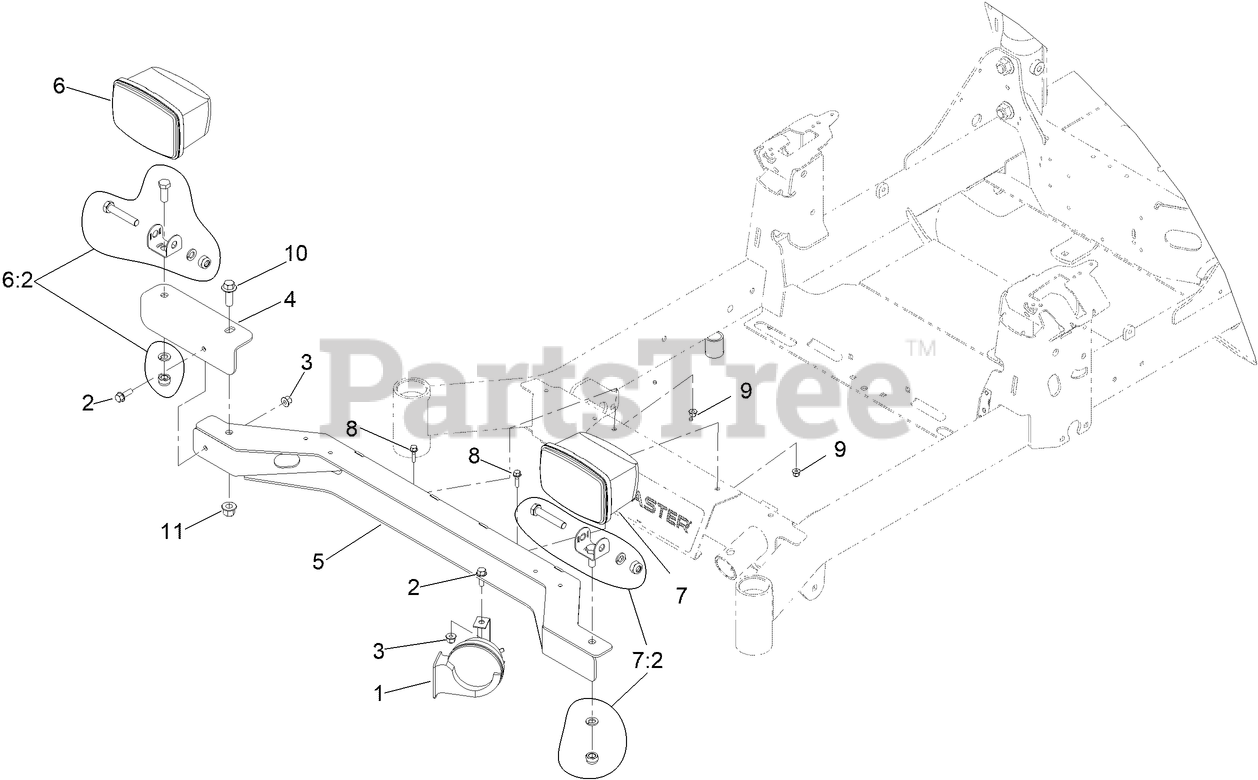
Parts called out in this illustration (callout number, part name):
2	SCREW-HHF
3	NUT-FLANGE, NI
4	BRACKET-EXTENSION, RIGHT
5	LIGHT-BRACKET, FRONT [BL
6	RH LIGHT ASM
6:2	LIGHT MOUNT KIT
7	LH LIGHT ASM
7:2	LIGHT MOUNT KIT
8	SCREW-HHF
9	NUT-FLANGE, NI
10	SCREW-HHF
11	NUT-FLANGE, NI
